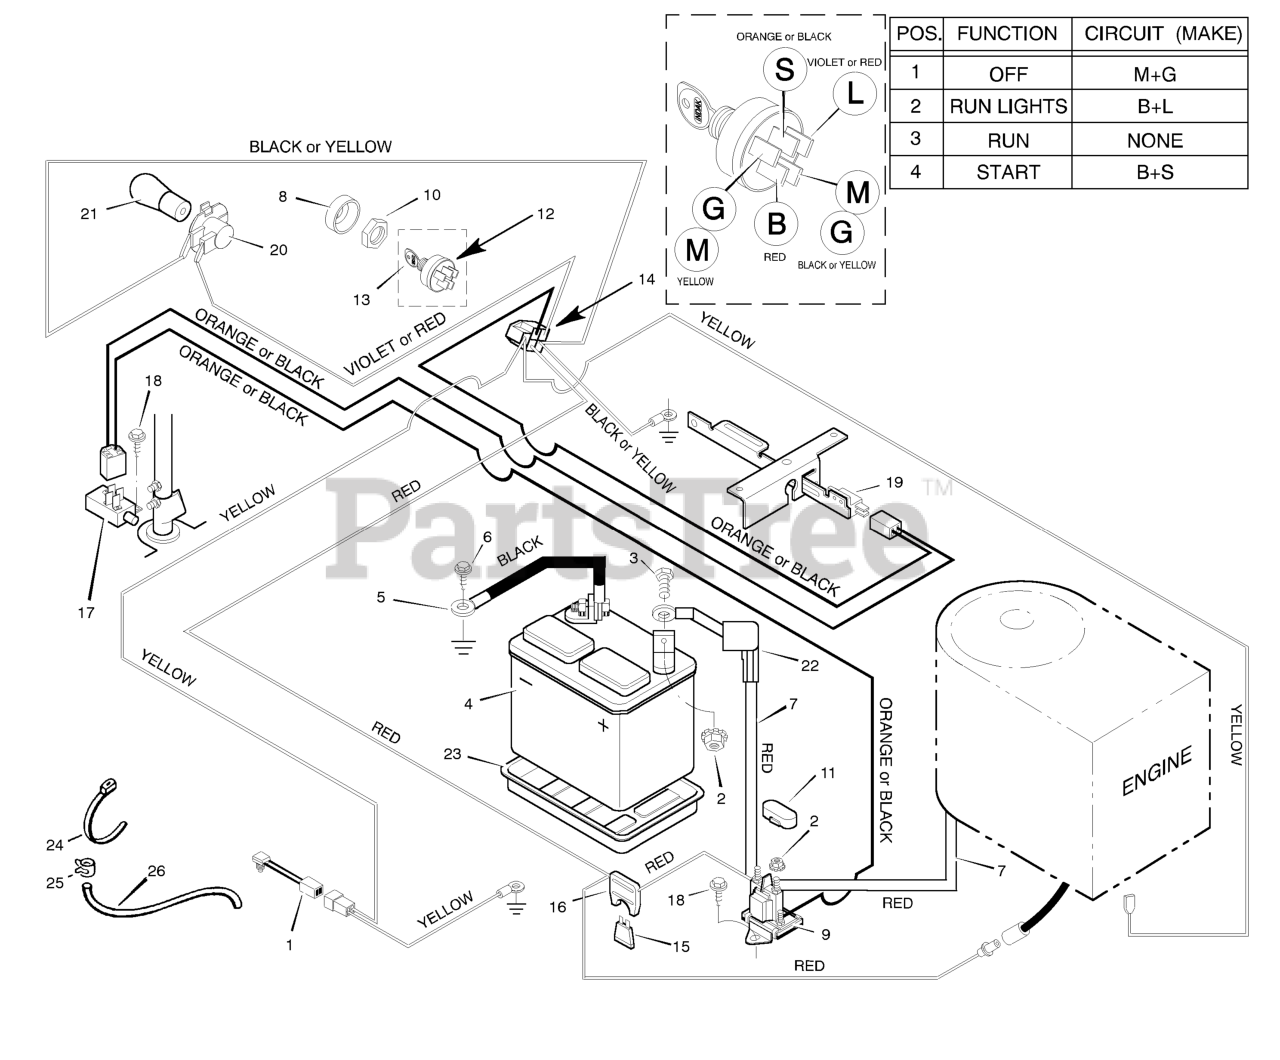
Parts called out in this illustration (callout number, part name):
1	Switch, Seat Sensor
2	Locknut
4	Battery
5	Cable, Battery Ground
7	Cable, Red Battery
8	Cap, Ignition
9	Solenoid
10	Nut, Hex
11	Cover, Solenoid
12	Switch, Ignition
13	Key, Ignition
14	Harness, Chassis Wire
16	Holder, Fuse
17	Switch, Limit
19	Switch, Limit
20	Socket, Light
21	Bulb, Light
22	Cover, Terminal
23	Tray, Battery
26	Tube, Drain
